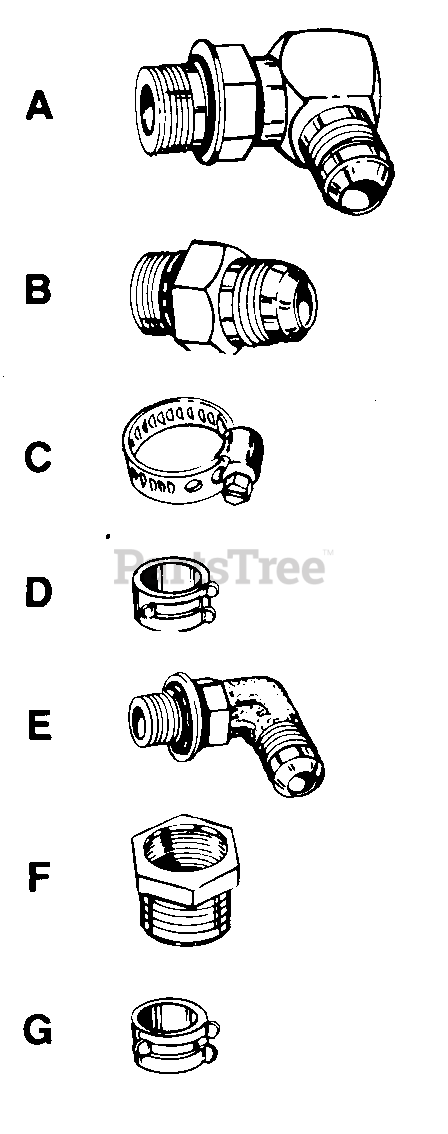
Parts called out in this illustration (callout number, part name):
A	7/8-14 SAE Boss to 3/4-16 JIC.
B	Adapter "O"-Ring:Boss to Male JIC.
C	Hose Clamp .406 Dia.for Ref. No. 9
D	Hose Clamp 3/8" Dia.
E	1/2-20 SAE Boss to 1/2-20 JIC.
F	Pipe Reducer 1/2-14 to 3/8-18 NPT
G	Hose Clamp .37 Dia. Finish Green Paint
